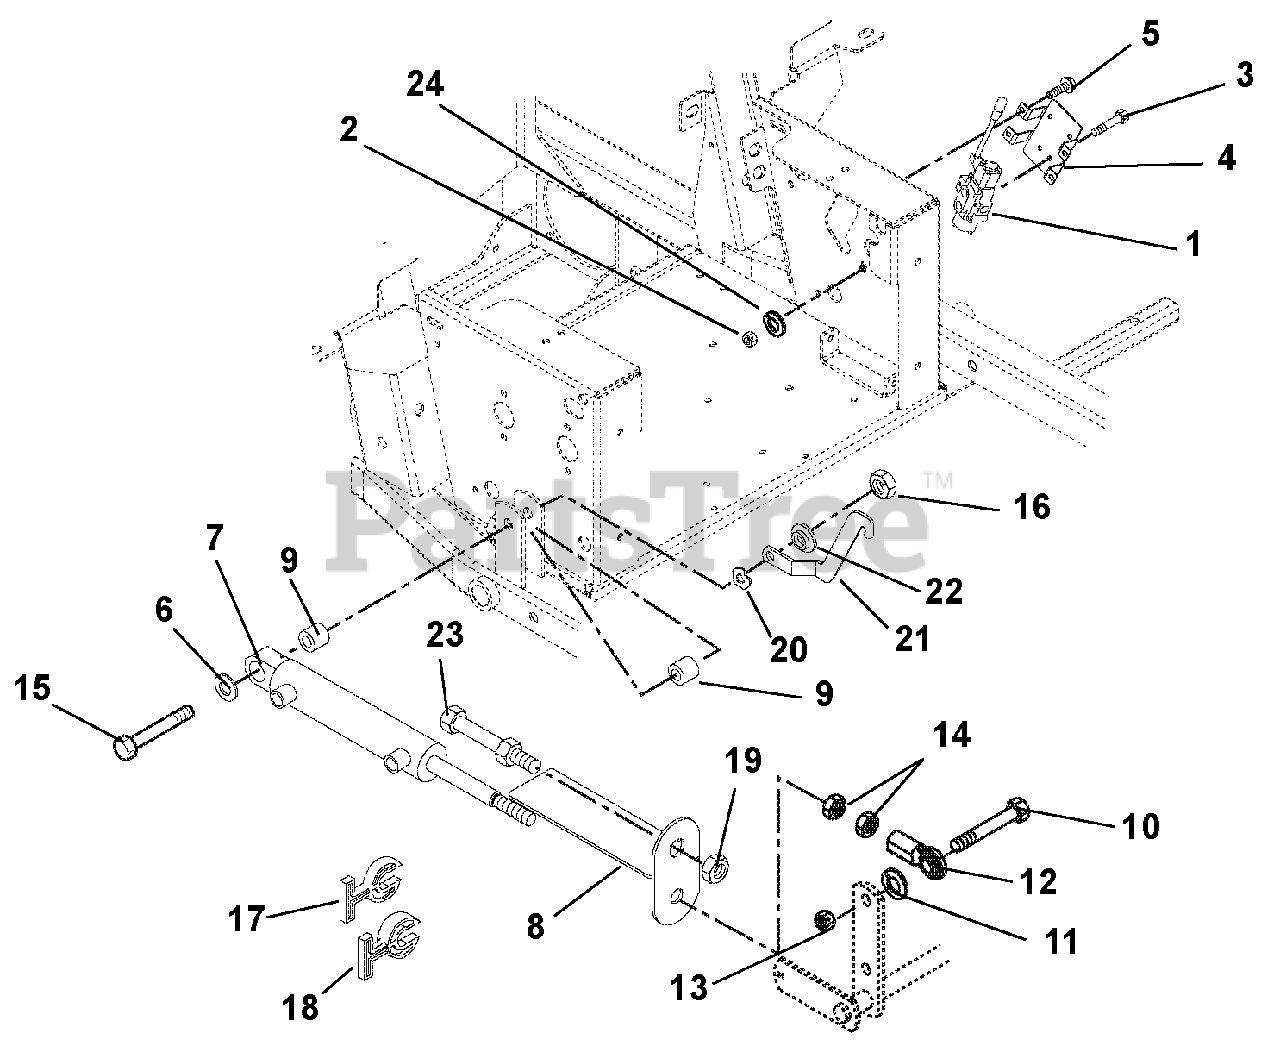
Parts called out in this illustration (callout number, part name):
1	Valve, Hydraulic
2	Nut, Locking Center .31-18
3	Bolt, Hex .31-18 x 2.00 Grade 5
4	Bracket, Valve Mounting
5	Screw, Tapping .38-16 x .50 Hex Washer Head
6	Washer, Flat Steel .515 x 1.625 x .25
7	Cylinder, Lift
8	Strap, Height of Cut Indicator
9	Bushing .516 x 1.00 x 1.05
10	Bolt, Hex .62-11 x 2.25 Grade 8
11	Washer, Lock .62 x .156
12	Rod End, Female .625 Right Hand
13	Nut, Locking Center .62-11
14	Nut, Jam .625-18
15	Bolt, Hex .50-13 x 3.75 Grade 5
16	Nut, Locking Top Flange .50-13
17	Stop, Cylinder .34 Thick
18	Stop, Cylinder .68 Thick
19	Nut, Jam .75-16
20	Washer, Wave .076 x 1.12 x .08
21	Latch, Floor Board
22	Bushing, Flange .515 x .75 x .275 x 1.12
24	Washer, Lock .31 x .078 Reg
